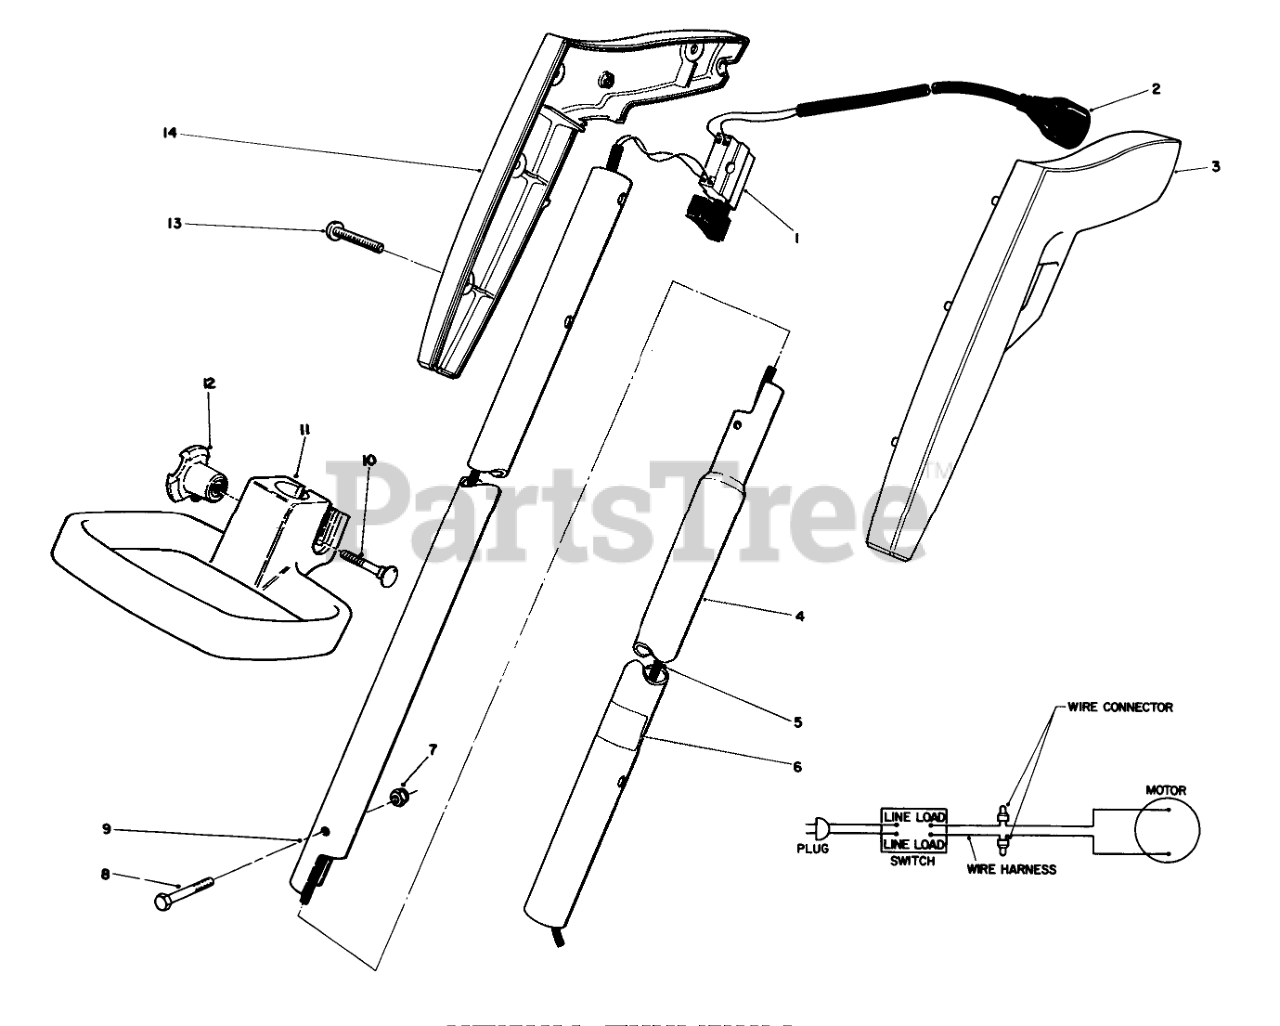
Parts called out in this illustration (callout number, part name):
1	SWITCH SINGLE SPEED
2	Cord-Power
3	Grip L.H.
4	Tubing-Lower Extension
5	WIRE HARNESS
6	REP. SERIAL PLT
7	NUT-LOCK, NI
8	HEX HD MACHINE SCREW
9	UPPER EXT TUBING
10	BOLT-CARR
11	Handle
12	Knob
13	Screw
14	R.H. GRIP
